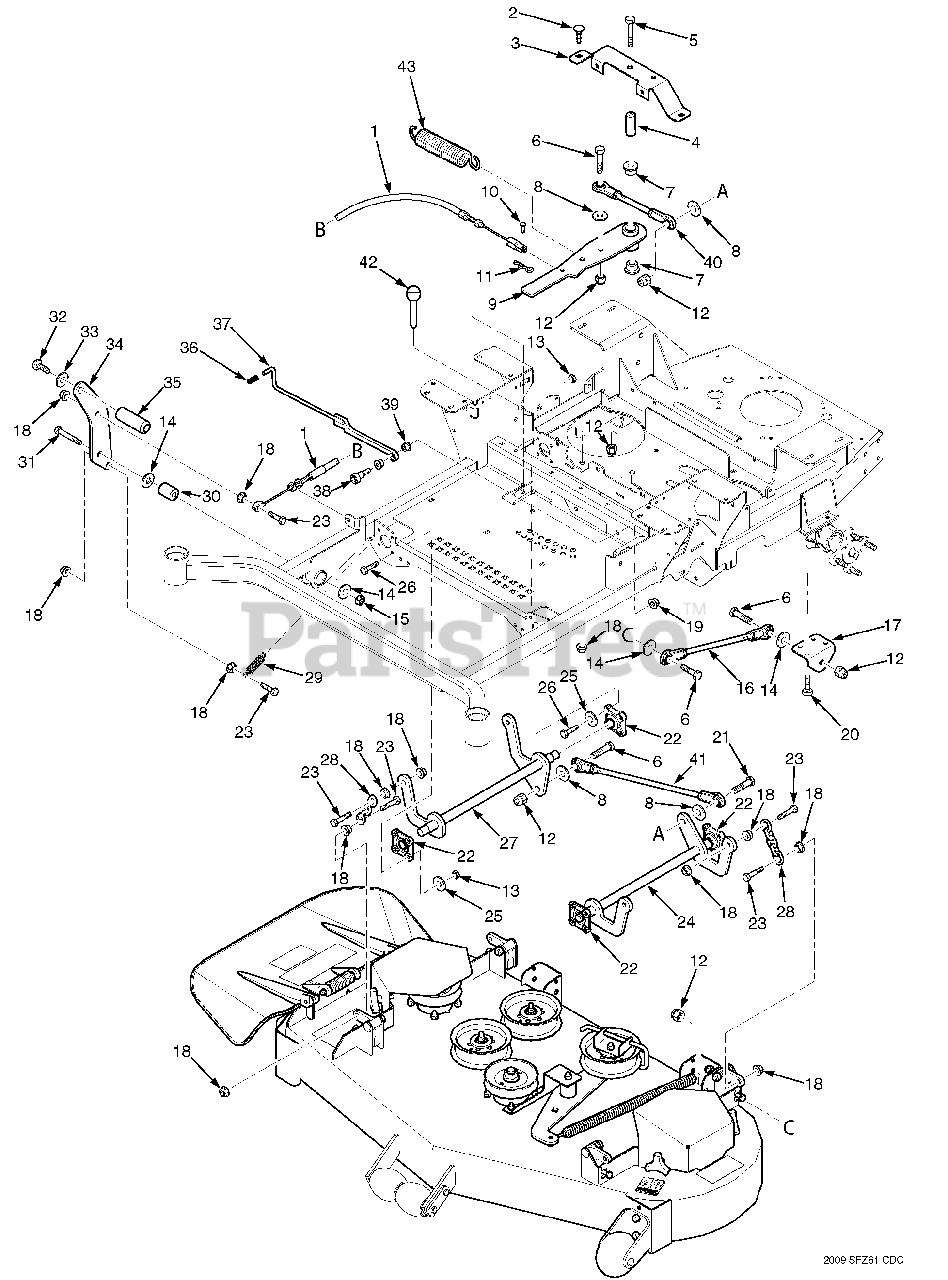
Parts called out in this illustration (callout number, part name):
1	Cable, Deck Lift
2	Bolt, Carriage 3/8-16 x 3/4"
3	Support, Idler Arm
4	Spacer, Deck Lift Pivot
5	Bolt, Hex Head 1/2-13 x 3-3/4"
6	Bolt, Hex Head 1/2-13 x 1-3/4"
7	Bearing
8	Flatwasher, 1/2-.531 x 1.06 x .095
9	Deck Lift Bellcrank Assembly
10	Clevis Pin, 5/16 x 3/4"
11	Hair Pin, .094 x 1.62"
12	Nut, Elastic Stop 1/2-13
13	Nut, Elastic Stop 5/16-18
14	Flatwasher, 1/2-.562 x 1.375 x .109
15	Nut, Center Lock 1/2-13
16	Linkage, Push Arm
17	Bracket, Push Arm Link
18	Nut, Serrated Flange 3/8-16
19	Nut, Elastic Stop 3/8-16
20	Bolt, Hex Head 5/16-18 x 3"
21	Bolt, Hex Head 1/2-13 x 2-1/2"
22	Bearing, Deck Lift
23	Bolt, Hex Head 3/8-16 x 1-1/2"
24	Weldment, Deck Lift LH
25	Flatwasher, 1/4-.312 x .750 x .065
26	Bolt, Hex Head 5/16-18 x 1"
27	Weldment, Deck Lift RH
28	Chain, Deck lift
29	Spring, Deck Lift
30	Sleeve, Deck Lift Pivot
31	Bolt, Hex Head 1/2-13 x 3"
32	Bolt, Head Socket 5/8-11 x 1-1/2"
33	Lockwasher, 5/8 Spring
34	Pedal, Foot Bracket
35	Foot Pedal
36	Grip, Deck Latch
37	Weldment, Deck Latch
38	Bolt, Shoulder 1/2 x 1/2
39	Bearing
40	Linkage Assembly, Deck Lift
41	Linkage Assembly, Deck Lift
42	Pin, Height Adjuster
43	Spring, Deck Lift
